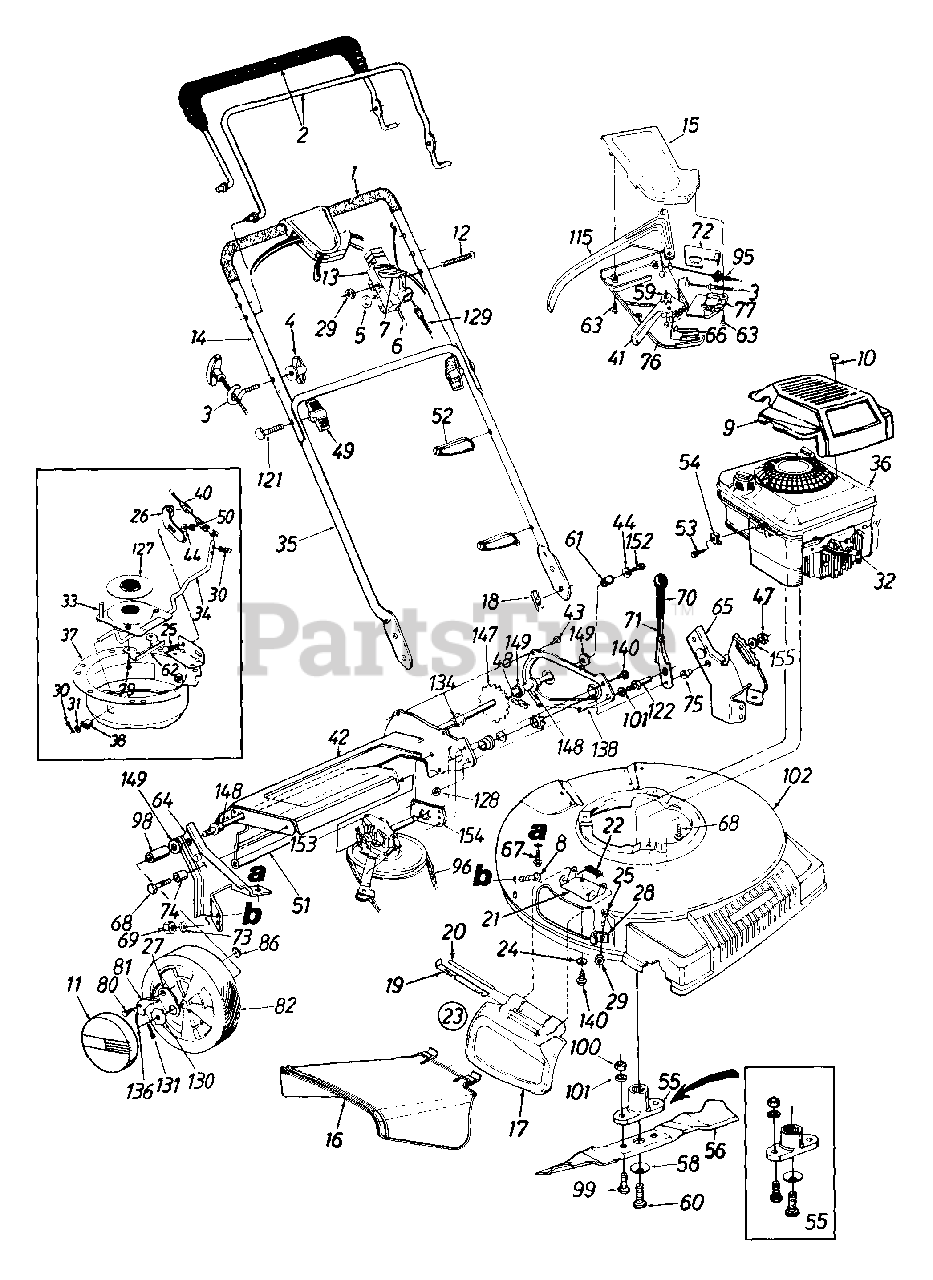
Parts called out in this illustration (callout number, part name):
1	Grip
3	Rope Guide
4	Handle Knob 1/4-20 Thd.
5	Curved Spring Wash..66" I.D.
6	Throttle Wire - 55" Lg.
7	Throttle Lever
8	Carriage Bolt 5/16-18 x .62" Lg.
9	XTE Engine Shroud (Black)
10	Hi-Lo Screw #10 x 1.25" Lg.
11	Hub Cap
12	Oval C-Sunk Mach. Scr.
13	Throttle Body
14	Upper Handle
15	Upper Control Housing
16	Side Chute Deflector
17	Mulch Plug
18	Internal Cotter Pin 5/16" Dia.
20	Hinge Pin
22	Torsion Spring
23	Mulch Plug Ass'y. Comp.
24	Bell-Wash..265" I.D. x .75" O.D.
25	Carriage Bolt 1/4-20 x .5" Lg.
30	Cotter Pin 3/32" Dia. x .75"
31	Fl-Wash..328" I.D. x .68"
32	Spark Plug Insulator
33	Lower Pulley Half Ass'y.
34	Shift Rod
36	Engine - 5 H.P.
40	6 Spd. Cable
41	6 Spd. Shift Lever
44	Bell-Wash. 1/4" I.D.
47	Hex Patch L-Nut 3/8-24 Thd.
48	#48 Chain .500" Pitch x 38 Links
49	Hand Knob
50	Hex L-Nut 1/4-20 Thd.
51	Rear Flap 4.8" x 17.5" Lg.
52	Cable Tie
53	Hex Wash. Hd. Scr. #10-32 x .62" Lg.
54	Casing Clamp
55	Blade Adapter Kit
56	21" Mulching Blade
58	Bell-Wash..47" I.D. x 1.14" O.D.
59	Gear Insert
60	Hex Bolt 7/16-20 x 2.5"
61	Spacer .513" I.D.
67	Hex B-Tap Scr. 5/16-18
68	Hex TT-Tap Scr. 3/8-16
69	Hex Nut 5/16-18 Thd.
71	Height Adj. Lever
72	6 Spd. Rack Cable Brkt.
73	Bell-Wash. 5/16" I.D.
74	Spacer .383" I.D.
75	Shld. Spacer .5" Dia.
76	Lower Control Housing
77	Cable Mounting Cap
79	Hex Wash. Hd. Tap Scr. 1/4-20 x .38" Lg.
80	Shld. Scr. .342" Dia. x .268
81	Pawl
82	Wheel Ass'y. Comp. (Gray Rim)
86	Weld Top L-Nut 1/4-20 Thd.
95	S.P. Cable
96	"V"-Belt
98	Sleeve .526" I.D.
99	Hex Bolt 3/8-24 x 1.0" Lg.
100	Hex Nut 3/8-24 Thd.
101	L-Wash. 3/8" I.D.
121	Curved Hd. Bolt 5/16-18 x 2" Lg.
122	Shld. Pin 1.43" Lg.
127	Pulley Half - Serrated
128	Hex Jam Nut 3/8-24 Thd.
129	Control Cable - 39"
130	Ratchet Wheel 1.62" O.D.
131	Cotter Pin 1/8" Dia. x 1"
134	Hex Flange Bearing
136	Spring - Nylon
147	Rear Shaft Ass'y. 21.44" Lg.
148	Hex Flange Brg. .506" I.D.
149	Fl-Wash..531" I.D. x .930"
152	Hex Bolt 1/4-20 x .62" Lg. (Gr. 5)
153	Transmission Comp. (See Breakdown)
155	Fl-Wash. .385" I.D. x .87" O.D.
